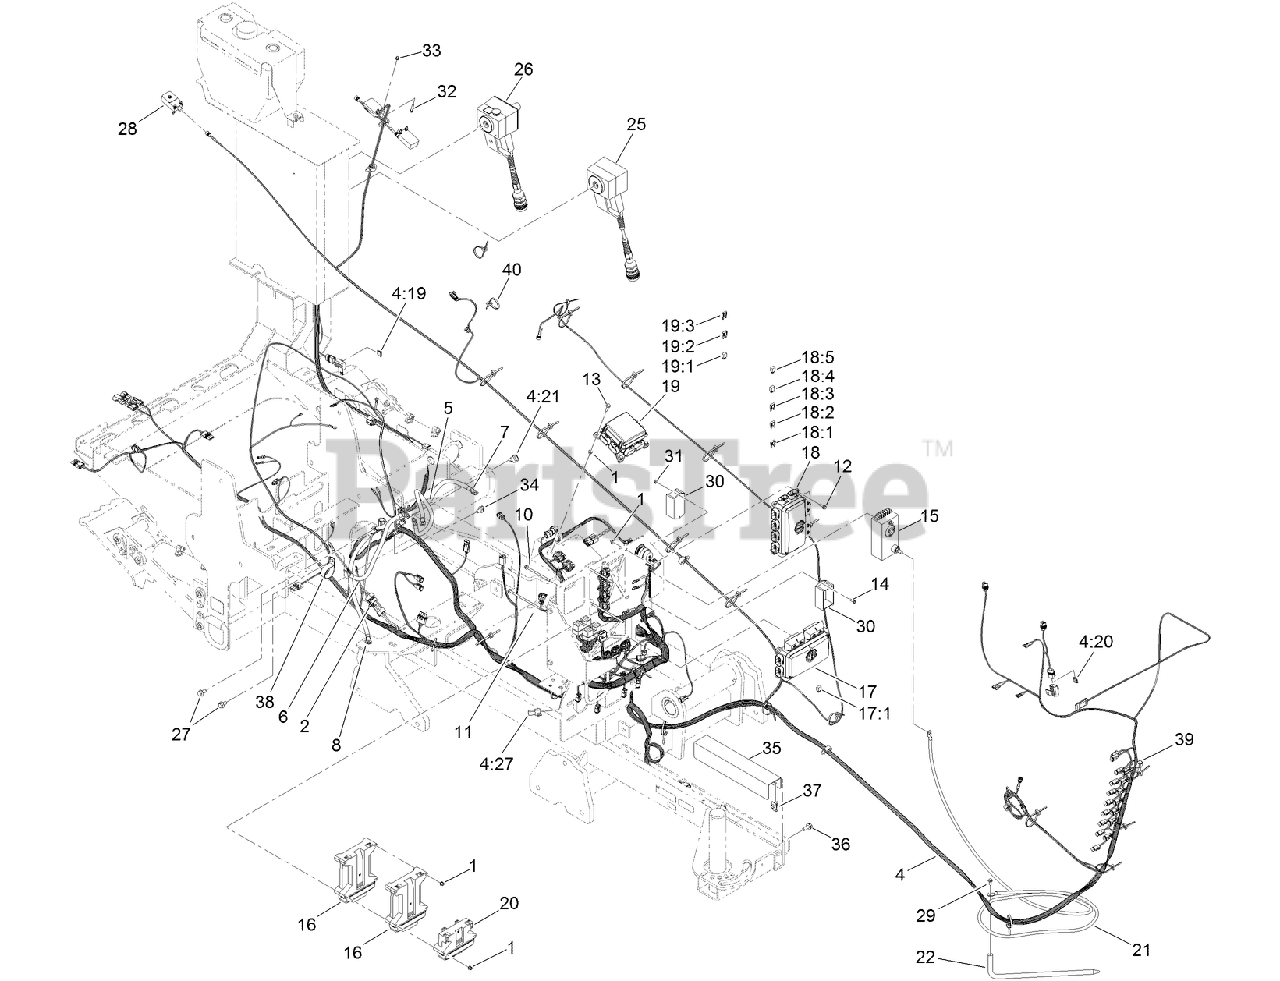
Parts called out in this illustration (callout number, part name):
1	NUT-FLANGE, NI
2	HARNESS-WIRE, FUSIBLE LINK
4	HARNESS-WIRE, MAIN
4:19	FUSE-BLADE, 15 AMP
4:20	FUSE-BLADE, 5 AMP
4:27	RESISTOR-120 OHM
5	CABLE-BATTERY, POSITIVE
6	CABLE-BATTERY, POSITIVE
7	CABLE-BATTERY, NEGATIVE
8	CABLE-BATTERY, NEGATIVE
10	SCREW-HHF
11	SCREW-HHF
12	SCREW-HHF
13	SCREW-HHF
14	SCREW-HWH
16	CONTROLLER-MICRO, 50-PIN
17	BOX-VEC, MAIN (A)
17:1	RELAY-280 ISO
18	BOX-VEC, MAIN (B)
18:1	FUSE-MINI BLADE, 30 AMP
18:2	FUSE-MINI BLADE, 2 AMP
18:3	FUSE-MINI BLADE, 20 AMP
18:4	RELAY-280 ISO
18:5	RELAY-280 ISO
19	BOX-VEC, MAIN (C)
19:1	RELAY-280 ISO
19:2	FUSE-MINI BLADE, 2 AMP
19:3	FUSE-MINI BLADE, 20 AMP
20	COMPUTER-EXPANDER, OUTPUT
21	CABLE-ALERT, STRIKE
22	BAR-STAKE, GROUND
25	LIFE JACKET ASM
26	TRAVEL PENDANT ASM
27	SCREW-HHF
28	SWITCH-PROXIMITY
29	SCREW-HHF
30	CONNECTOR-PACK, RESISTOR
31	NUT-LOCK, FLANGE
32	SCREW-HSH
33	NUT-HF
34	CLIP-TREE (W/TIE)
35	PLATE-GUARD, WIRE
36	SCREW-HHF
38	CLAMP-R
39	HARNESS-WIRE
40	TIE-CABLE
